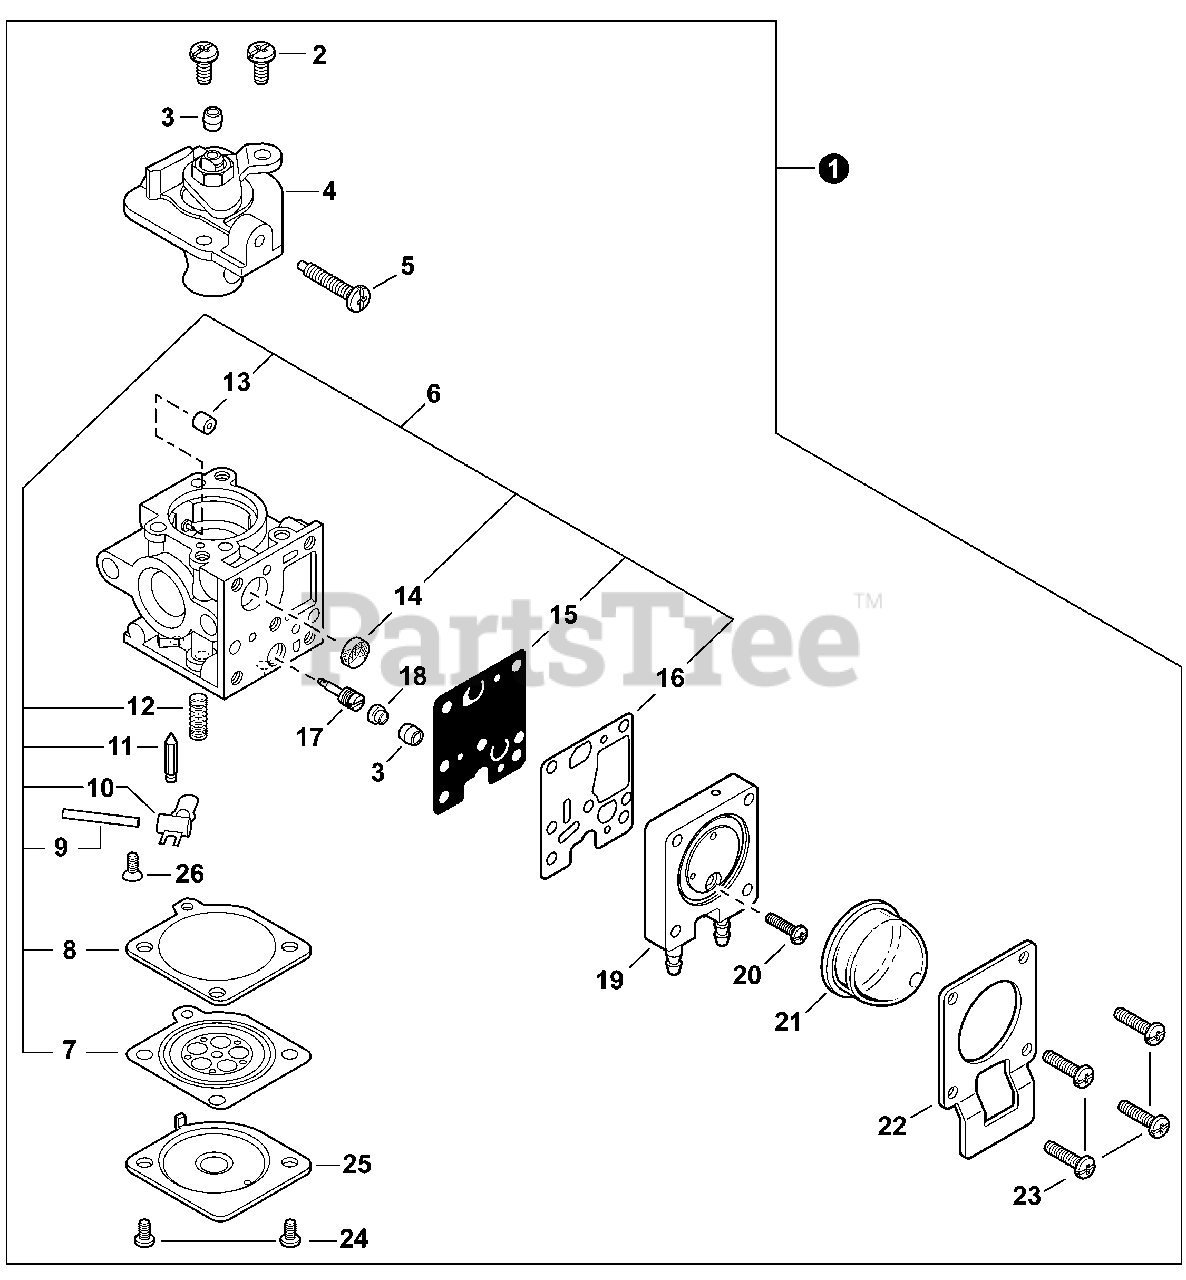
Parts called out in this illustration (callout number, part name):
1	CARBURETOR RE-110147B
4	COVER ASSY, ROTOR
5	SCREW, IDLE ADJUST
6	REPAIR KIT, CARBURETOR
7	DIAPHRAGM, METERING
8	GASKET, METERING DIAPHRAGM
9	PIN, METERING LEVER
10	LEVER, METERING
11	VALVE, INLET NEEDLE
12	SPRING, METERING LEVER
13	GUIDE, ROLLER
14	SCREEN, FUEL INLET
15	DIAPHRAGM, PUMP
16	GASKET, PUMP
17	NEEDLE, MIXTURE
18	CAP, LIMITER
19	BODY ASSY, PURGE
21	BULB, PURGE
22	RETAINER, PURGE BULB
25	COVER, METERING DIAPHRAGM
